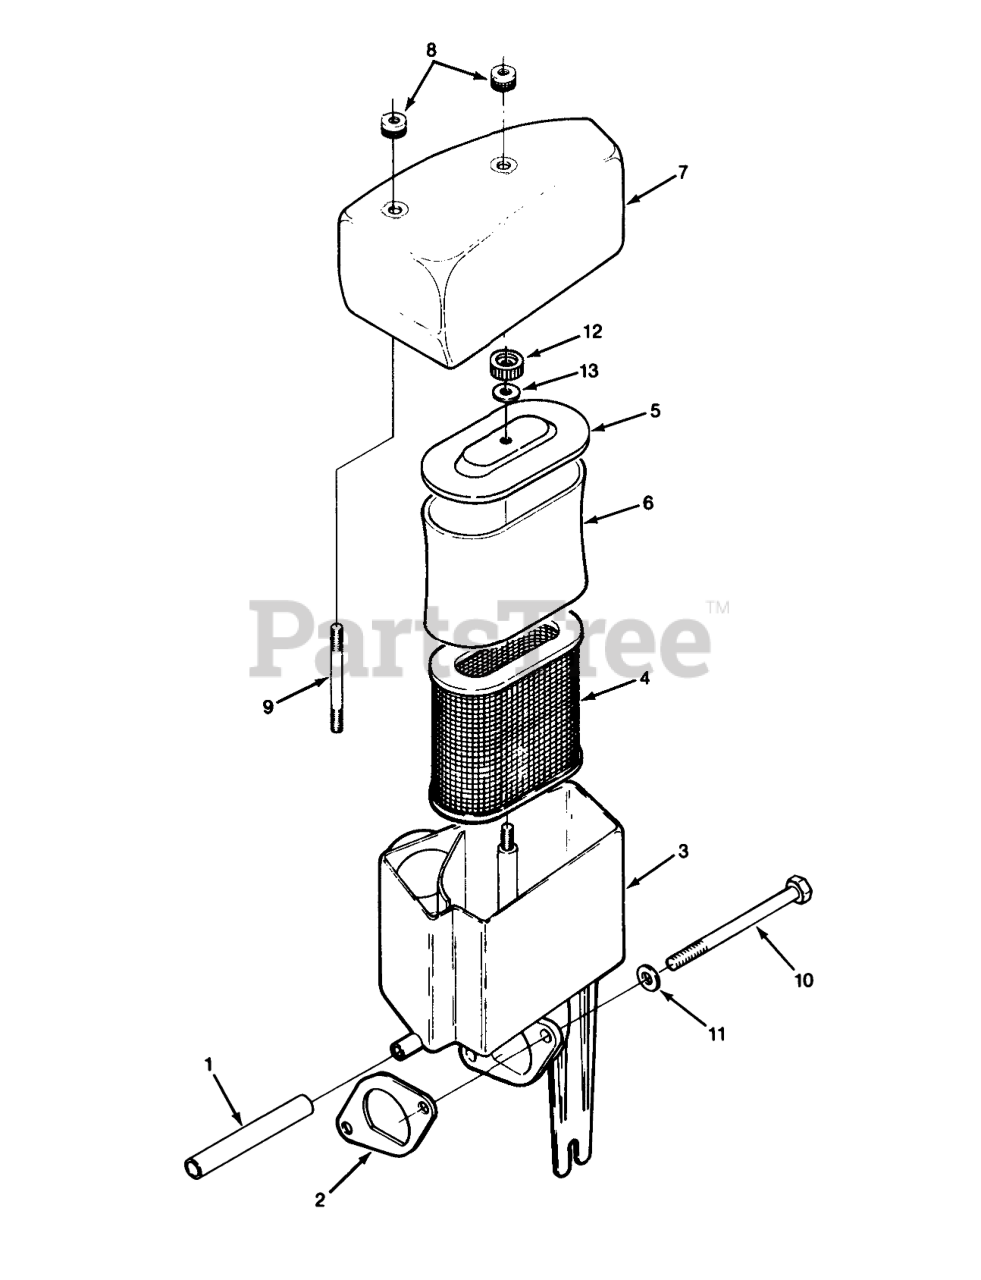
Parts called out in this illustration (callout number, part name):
1	HOSE-BRH 3/8"IDX91MM
2	Gasket
3	Adapter
4	Element
5	COVER-ELEMENT
6	WRAPPER-ELEMENT
7	Air Cleaner Cover
8	KNOB M6
10	HHCS-M8 X 100MM
11	Nut-M8
13	GROMMET
